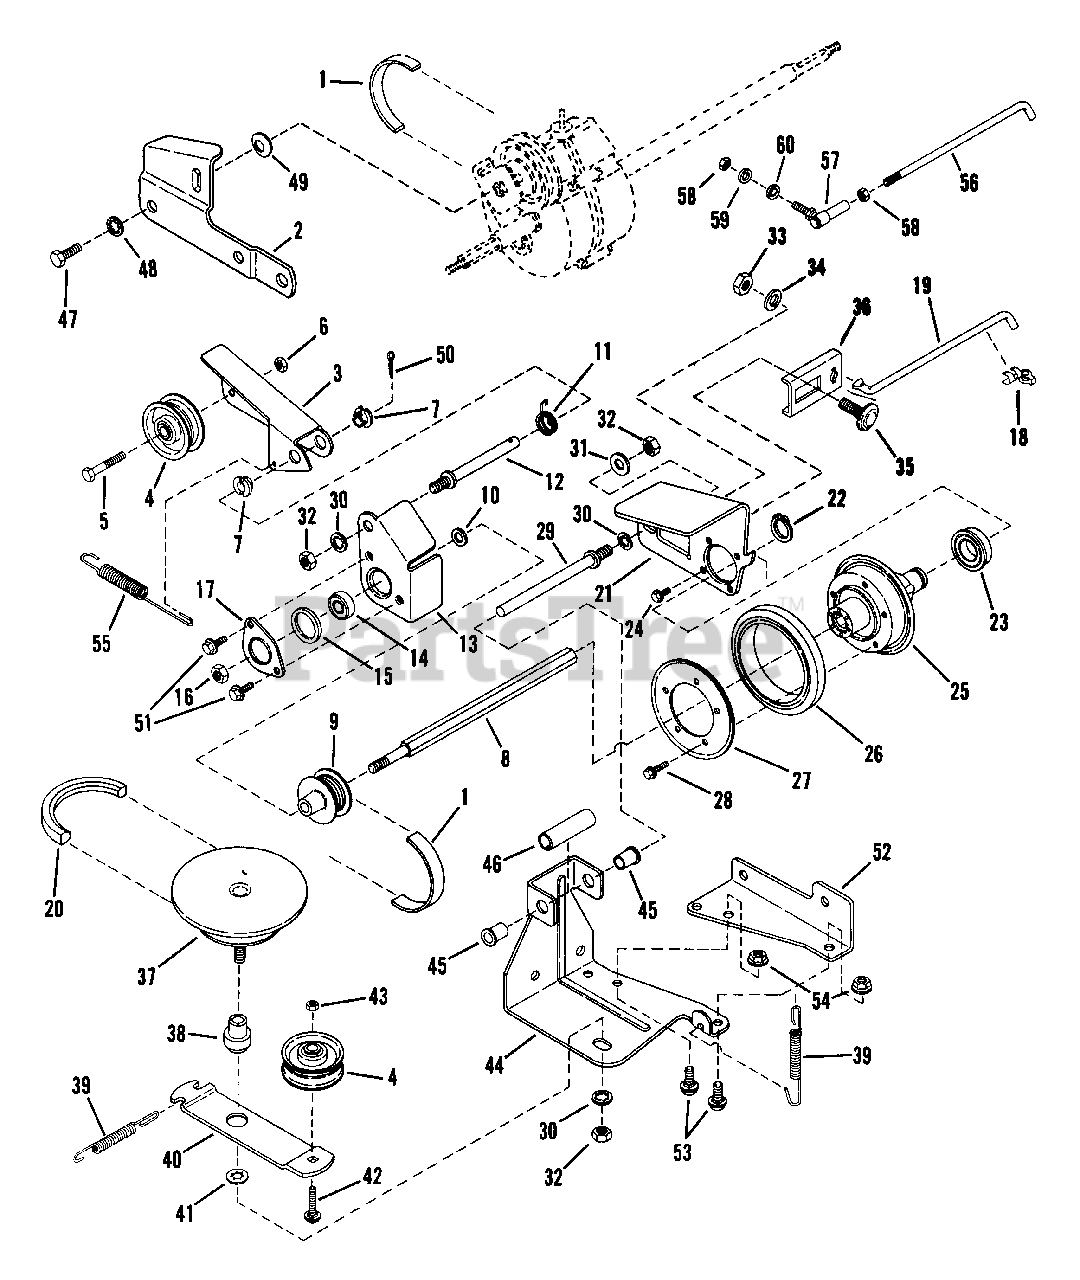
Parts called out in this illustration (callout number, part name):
1	BELT, Poly-Vee
2	LINK, Differential
3	Clutch Idler ASSEMBLY,
3	ARM, Clutch Idler
4	PULLEY, idler
5	CAPSCREW, 1/4-28 x 1-3/8" Hex Head
6	NUT, 1/4-28 Hex Lock
7	BUSHING, 3/8 I.D. Nylon
8	SHAFT, Hex
9	PULLEY
10	WASHER
11	SPRING, Torsion
12	STUD
13	HOLDER, Bearing
14	BEARING, Ball
15	O-RING
16	NUT, 3/8 Hex Center Lock
17	HOLDER, Bearing (Outer Half)
18	CLIP, 1/4 Right Arc (Transfer Rod)
19	ROD, Transfer
20	BELT, Engine Drive
21	PLATE, Thrust
22	RING, Retaining
23	BEARING, Ball
24	SCREW, #10-32 x 1/4" Self-Tapping Machine
25	ASSEMBLY, Hub
26	RING, Driven (Rubber Disc)
27	PLATE, Ring Retaining
28	SCREW, #10-24 x 1/2" Hex Washer Self-Tap (Torx)
29	GUIDE, Thrust Plate
30	WASHER, 3/8 Internal Tooth Lock
31	WASHER, 3/8" Flat
32	NUT, 3/8-24 Hex
33	NUT, 5/16-18 Hex
34	WASHER, 5/16 Split Lock
35	BOLT, 5/16-18 x 3/4 Carriage
36	CONNECTOR, Transfer Rod
37	ASSEMBLY, Drive-Disc
38	BUSHING
39	SPRING (Wheel Drive & Idler)
40	ARM, Idler
41	RETAINER, 3/8 Bolt
42	BOLT, 1/4-20 x 1-1/4" Carriage
43	NUT, 1/4-20 Hex Center Lock
44	ASSEMBLY, Deck Bracket
44	BRACKET, Deck
45	BUSHING, Flange
46	SPACER
47	SCREW, 5/16-18 x 1/2" Hex Head Cap
48	WASHER, 5/16 Internal Tooth Lock
49	WASHER, Spring
50	COTTER-PIN, 3/32 x 1/2"
51	SCREW, 1/4-20 x 1/2" Self-Tapping
52	BRACKET, Strap
53	BOLT, 5/16-18 x 5/8" Short Neck Carriage
54	NUT, 5/16-18 Hex Flange Lock
55	SPRING, Clutch
56	LINK, Transfer
57	JOINT, Ball
58	NUT, 1/4-28 Hex
59	WASHER, 1/4 Flat
60	WASHER, 1/4 Internal Tooth lock
